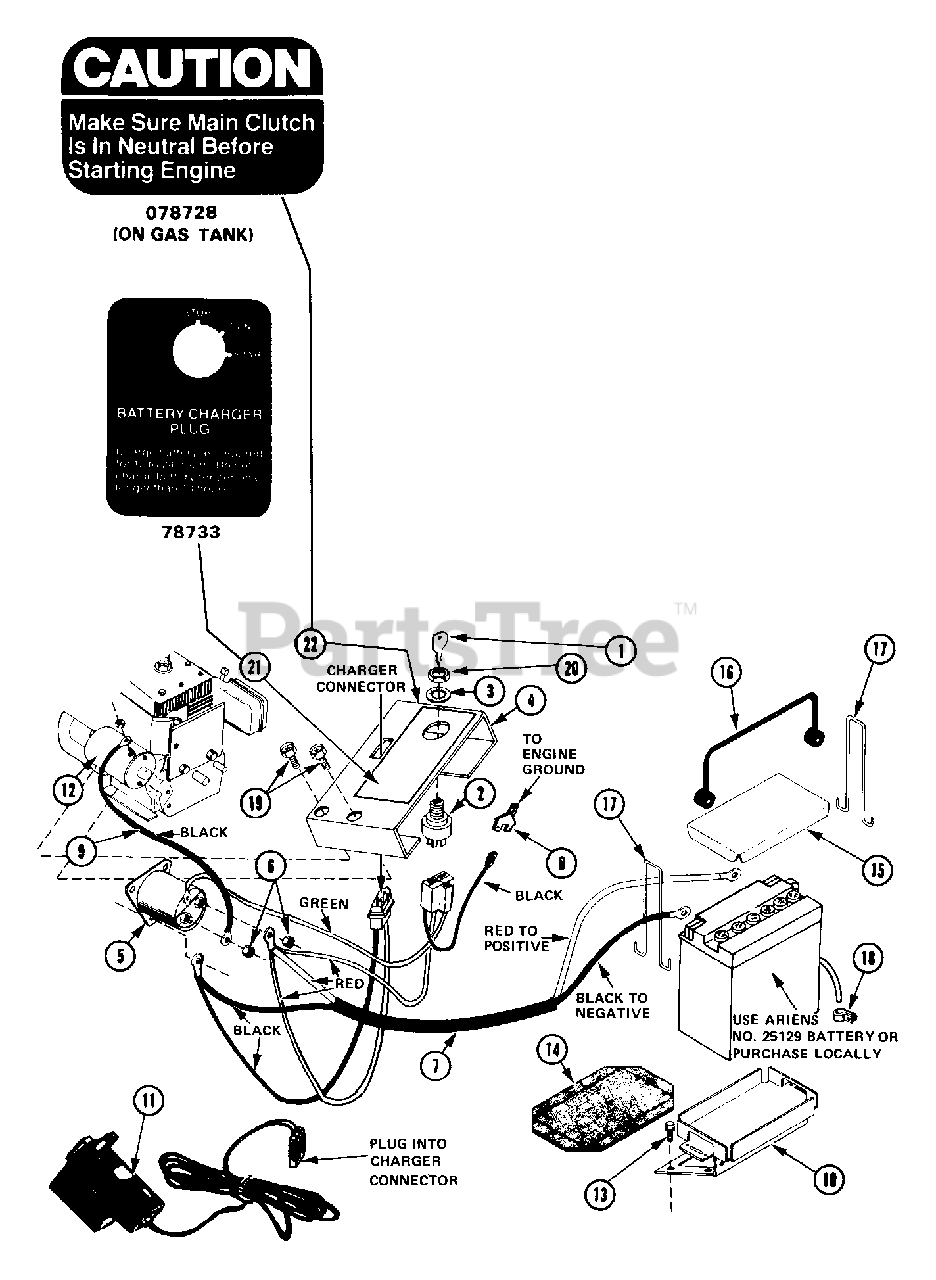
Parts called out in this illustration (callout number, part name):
1	KEYS
2	IGNITION SWITCH ASSEMBLY
3	WSHR-LK-INT .625X.045 PL
4	BRACKET ELECT START
5	SOLENOID,STARTER SWITCH
6	NUT-LK-CTR .250-20 PL
7	WIRING HARNESS
8	ADAPTER - CONNECTOR
9	GROUND CABLE
10	BATTERY TRAY
11	BATTERY CHARGER
12	STARTER MOTOR, 12 VOLT
13	BLT-SERHFWH .25-20X.50 PL
14	RUBBER PAD
15	BATTERY COVER
16	BATTERY STRAP
17	HOOK
19	SCR-CAP CR SEMS .25-20X.50 PL
20	NUT .625-32 ALUM
21	STARTER KIT DECAL
22	CAUTION DECAL
